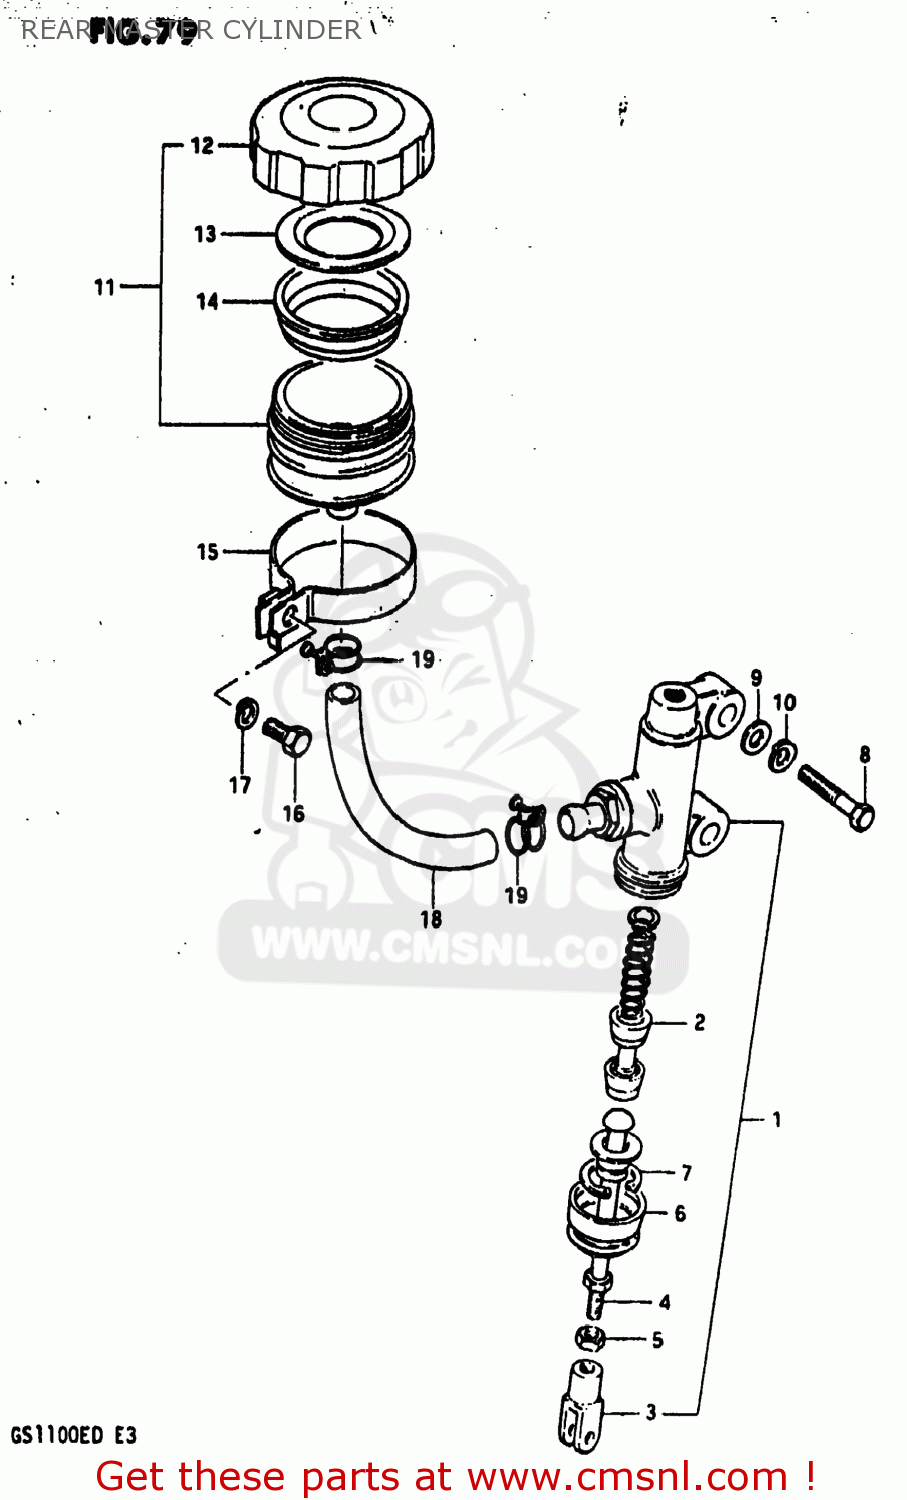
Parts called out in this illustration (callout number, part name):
1	CYLINDER ASSEMBLY,REAR MASTER
2	PISTON/CUP SET
3	YOKE
4	ROD,PUSH
5	NUT,MASTER CYLINDER
6	BOOT
7	CIRCLIP
8	BOLT (8X30)
9	WASHER
10	LOCK WASHER
11	TANK ASSEMBLY,RESERVOIR
12	CAP
13	PLATE,DIAPHRAGM
14	DIAPHRAGM
15	CLAMP
16	BOLT, UPPER
17	LOCK WASHER
18	HOSE,RESERVOIR TANK
19	CLAMP
